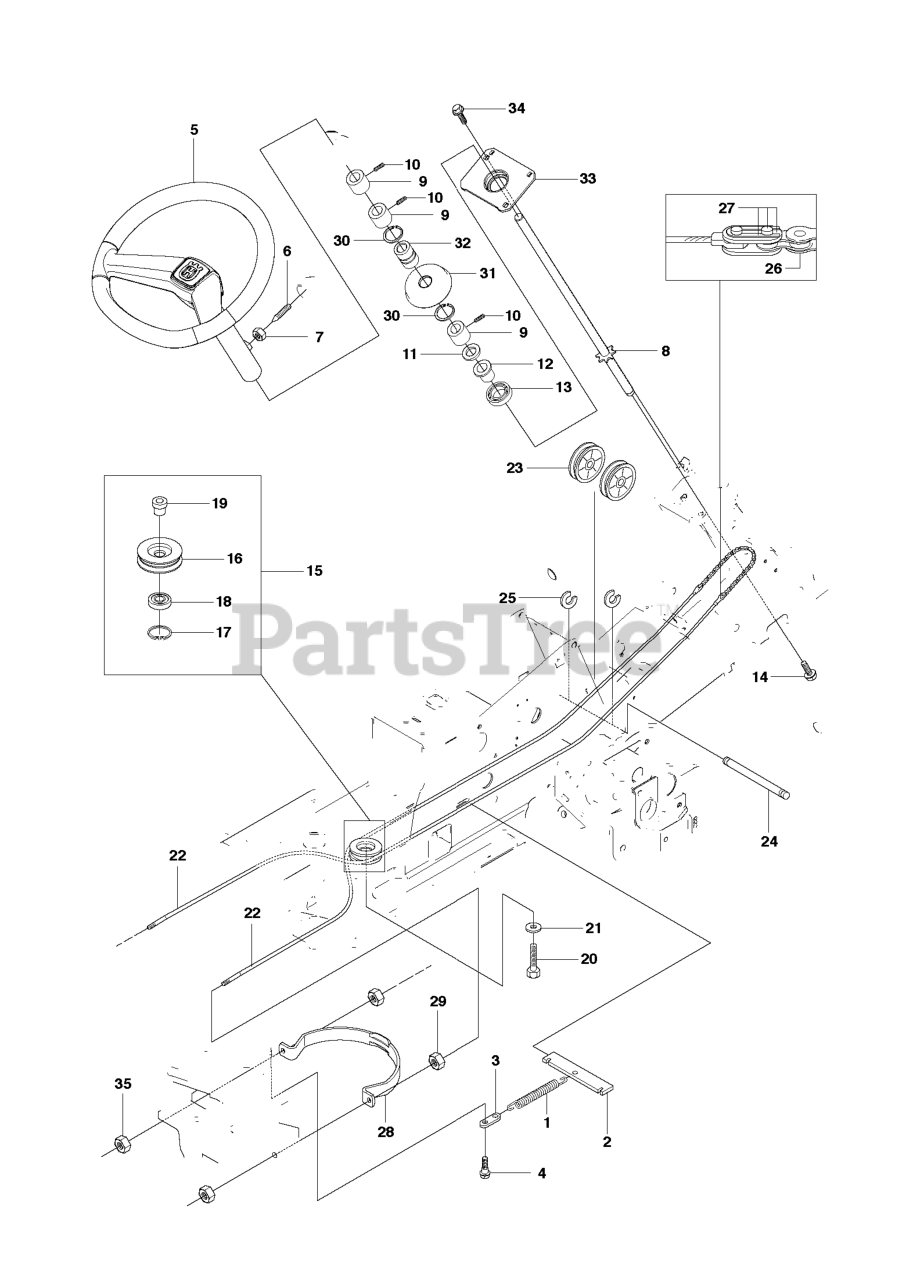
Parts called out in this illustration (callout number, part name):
2	SPRING BRACKET
7	NUT
8	STEERING ROD
9	SPACER
13	BALL BEARING 6004-2RS1
17	CIRCLIP SGH 47
18	BALL-BEARING 6204-2RS
22	RP STEERING CABLE COMPLETE
24	SHAFT
25	RETAINING RING
26	STEERING CHAIN
28	WIRE GUIDE
29	NUT
30	RETAINING RING SGA 25
35	NUT
